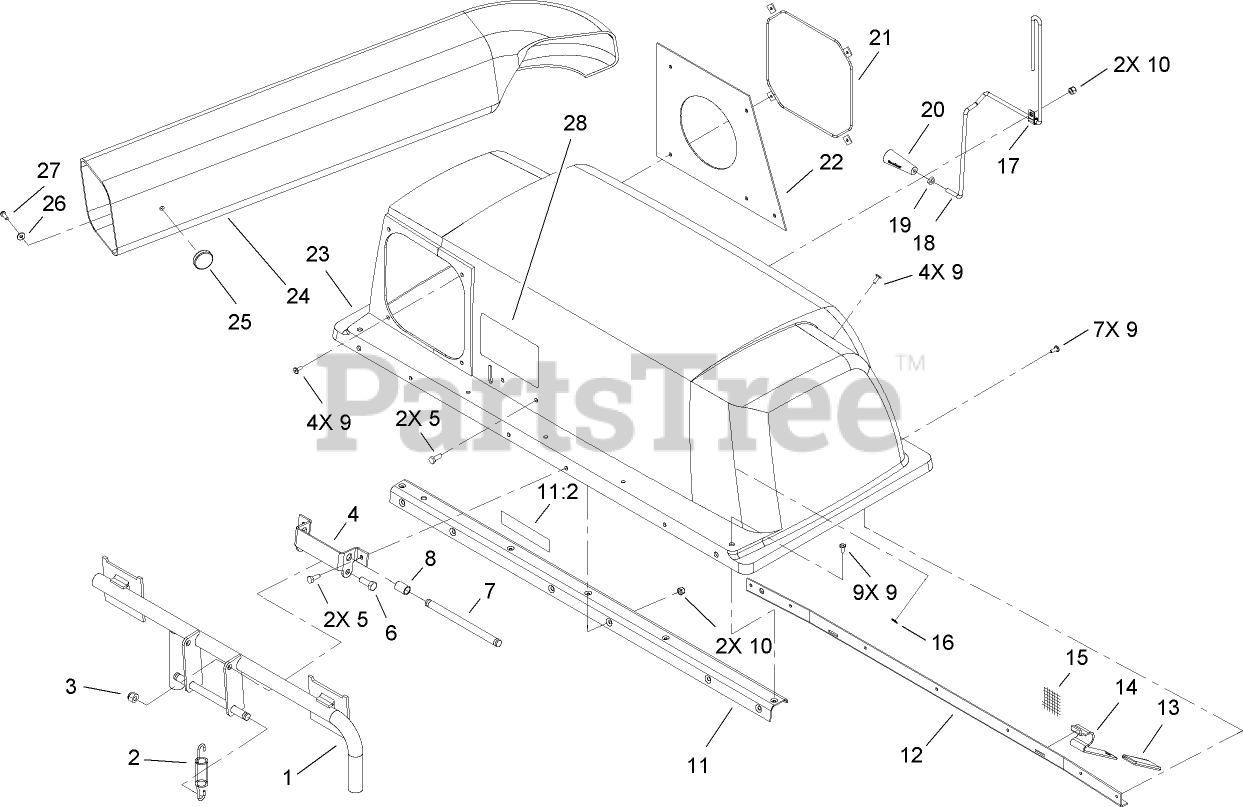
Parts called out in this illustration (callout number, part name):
1	FRAME ASM
2	SPRING-EXTENSION
3	NUT-LOCK, NI
4	HINGE-BAG, TOP
5	SCREW-HH
6	SCREW-HH
7	PIN-SPRING
8	SPACER
9	RIVET-BLIND
10	NUT-LOCK, NI
11	STIFFENER ASM
11:2	DECAL-CAUTION
12	SUPPORT-SCREEN
14	LATCH-BAGGER, TOP
15	SCREEN-BAGGER
16	WASHER-FLAT
17	CLAMP
18	FEELER-FILL, BAG
19	NUT-JAM
20	HANDLE-TAPERED
21	CLAMP-SEAL
22	SEAL-CHUTE
23	TOP-BAGGER
24	CHUTE-DISCHARGE
26	WASHER-PLAIN
27	SCREW-PPHTF
28	DECAL
